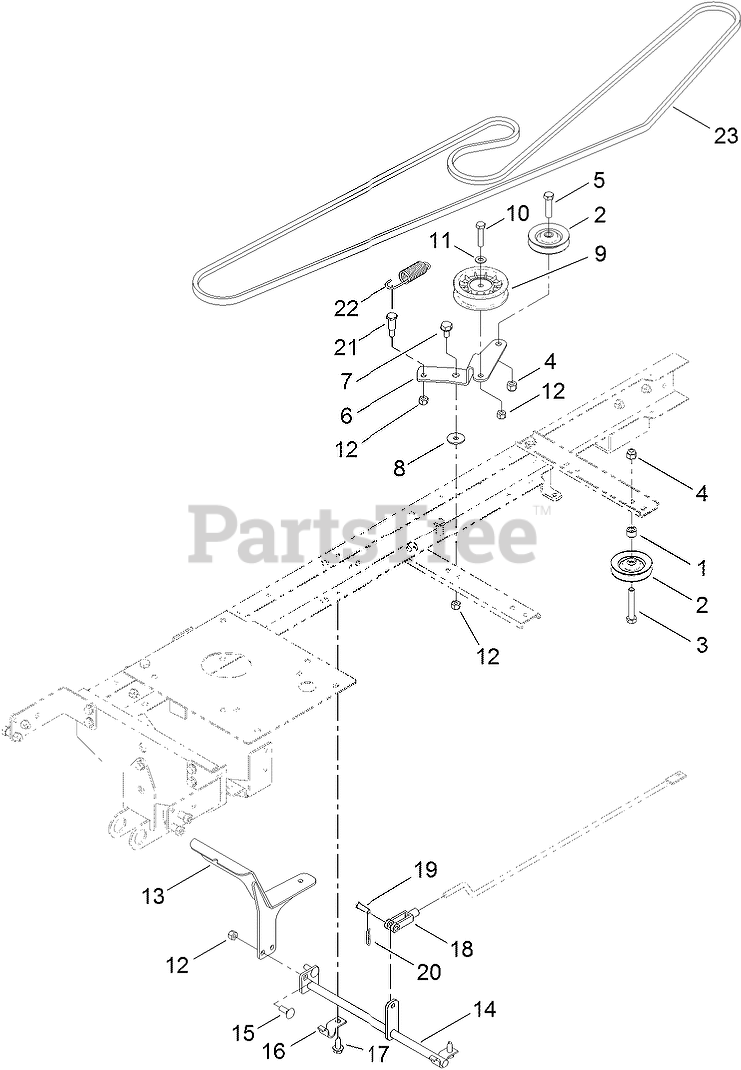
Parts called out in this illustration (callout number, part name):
1	BUSHING-LEVER, LIFT
2	PULLEY-IDLER
3	SCREW-HH
4	NUT-LOCK, NI
5	SCREW-HH
6	BRACKET-IDLER
7	BOLT-SHOULDER
8	WASHER-PIVOT
9	PULLEY-IDLER
10	SCREW-HH
11	WASHER-PLAIN
12	NUT-LOCK, NI
13	PEDAL-CONTROL, MOTION
14	ARM-CONTROL, MOTION
15	SCREW-CARR
16	CLAMP-PIVOT, SHIFT
17	SCREW-HWH
18	YOKE-ADJUSTABLE
19	PIN-CLEVIS
20	PIN-COTTER
21	SCREW-SHOULDER
22	SPRING-EXTENSION
23	BELT-DRIVE, BLADE
